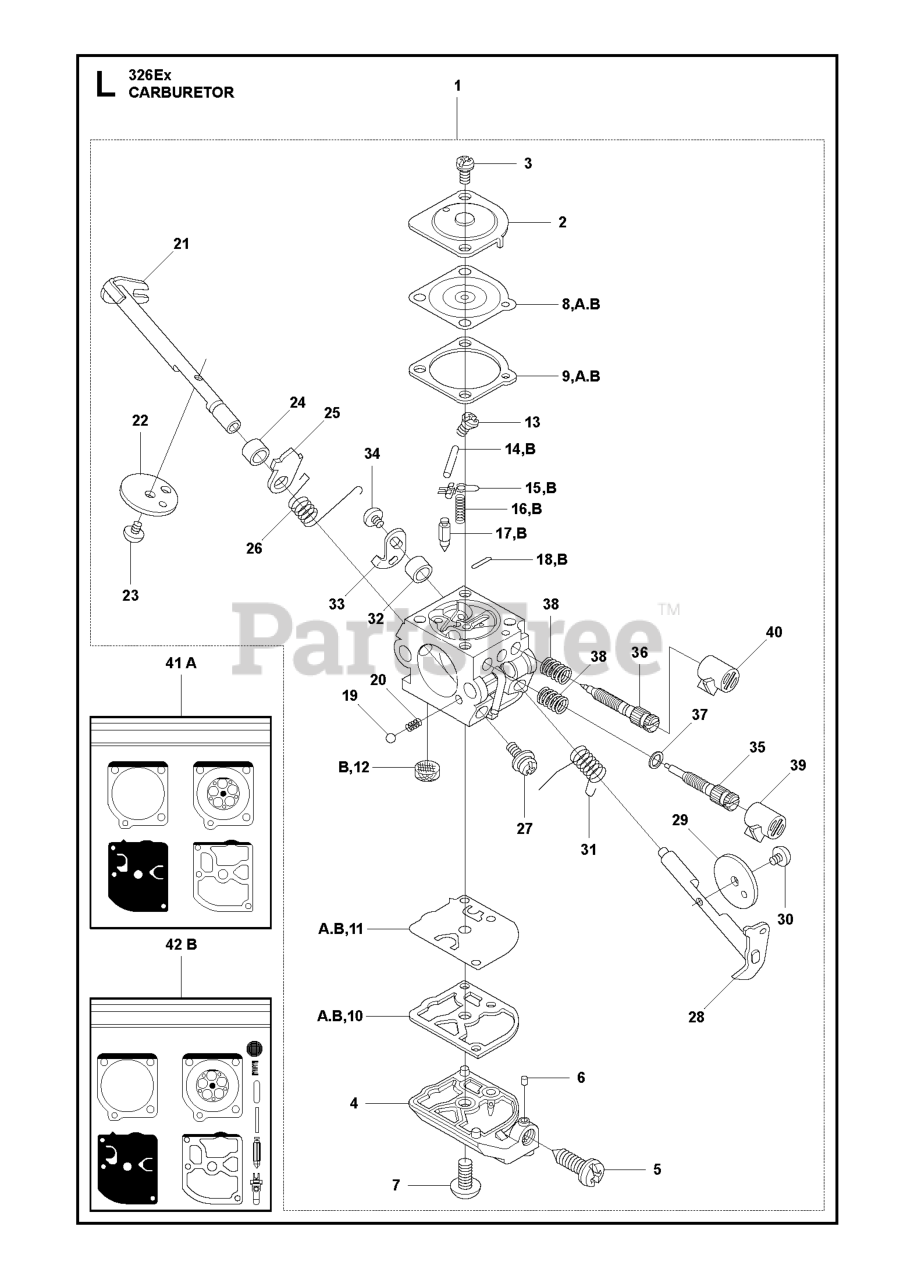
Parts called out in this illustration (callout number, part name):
1	CARBURETOR
11	PUMP DIAPHRAGM
14	PIN RETAINING SCREW
16	SPRING
17	INLET NEEDLE
21	CHOKE SHAFT
29	THROTTLE FLAP
31	SPRING THROTTLE
35	NEEDLE HIGH SPEED
36	LOW SPEED NEEDLE
38	SPRING
